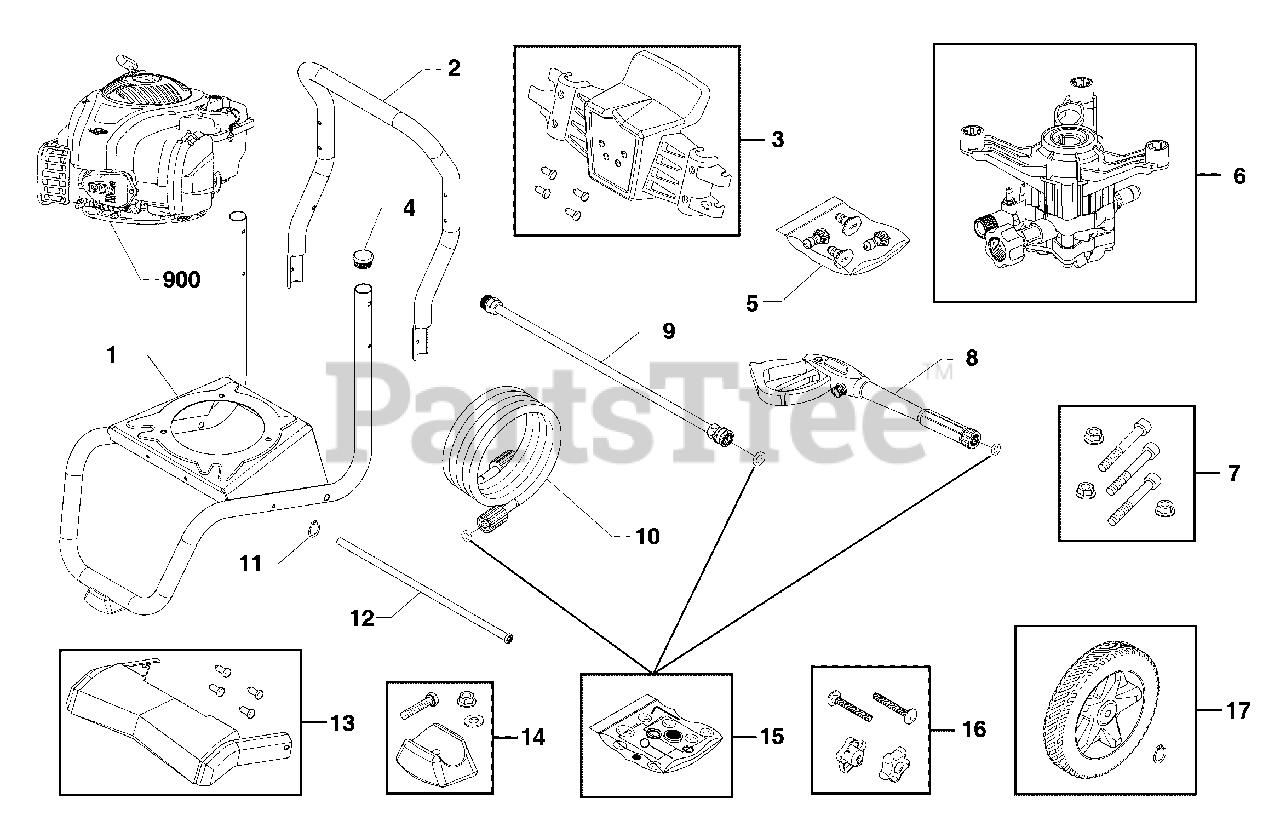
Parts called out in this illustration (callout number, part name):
5	KIT, QC Nozzles
7	KIT, Hardware, Pump Mounting
8	GUN
9	EXTENSION, QC
10	HOSE
14	MOUNT-VIBRATION
15	KIT-O-RING MAINTENANCE
16	KIT, Hardware, Handle
